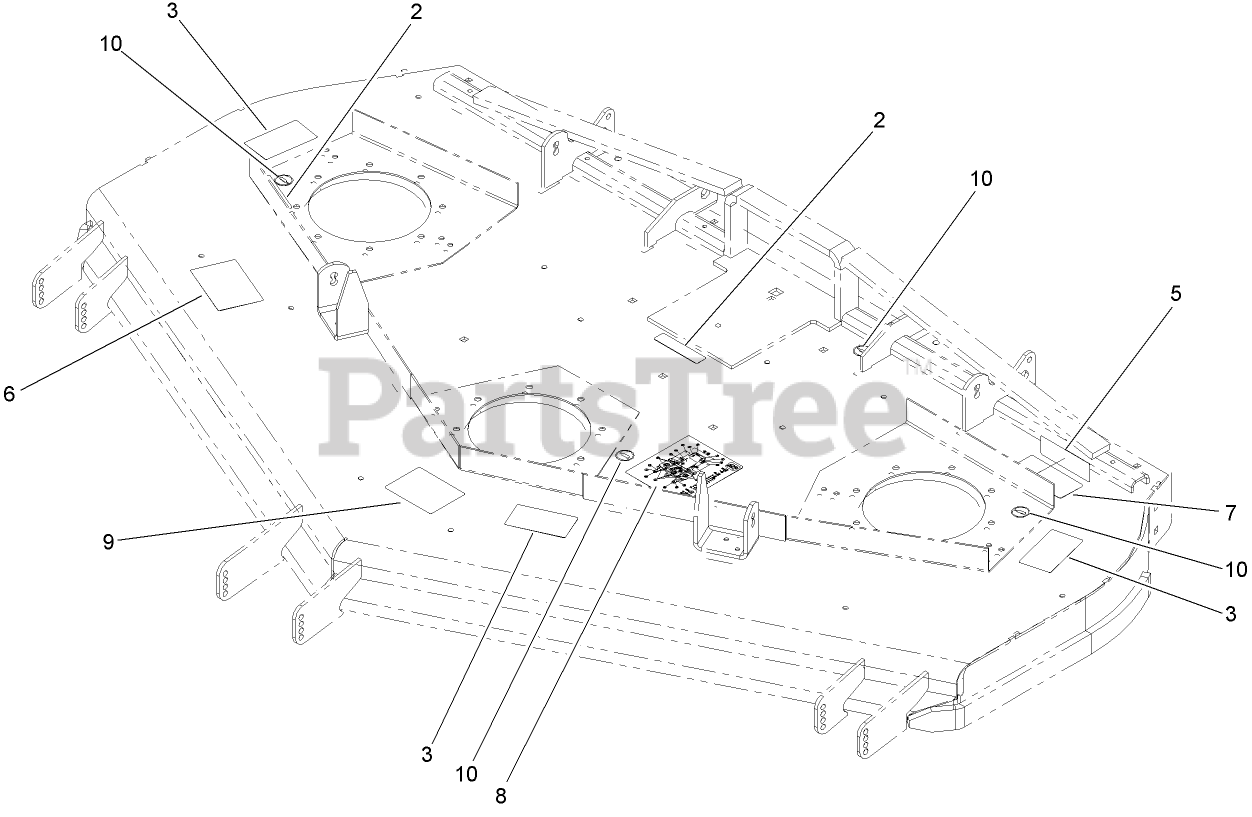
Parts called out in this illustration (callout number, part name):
2	DECAL-WARNING
3	DECAL-DANGER
6	DECAL
7	DECAL-TORQUE, BLADE BOLT
8	DECAL-SERVICE AID, BELT ROUTING CE
9	DECAL-ANTI SCALP
10	DECAL-GREASE
